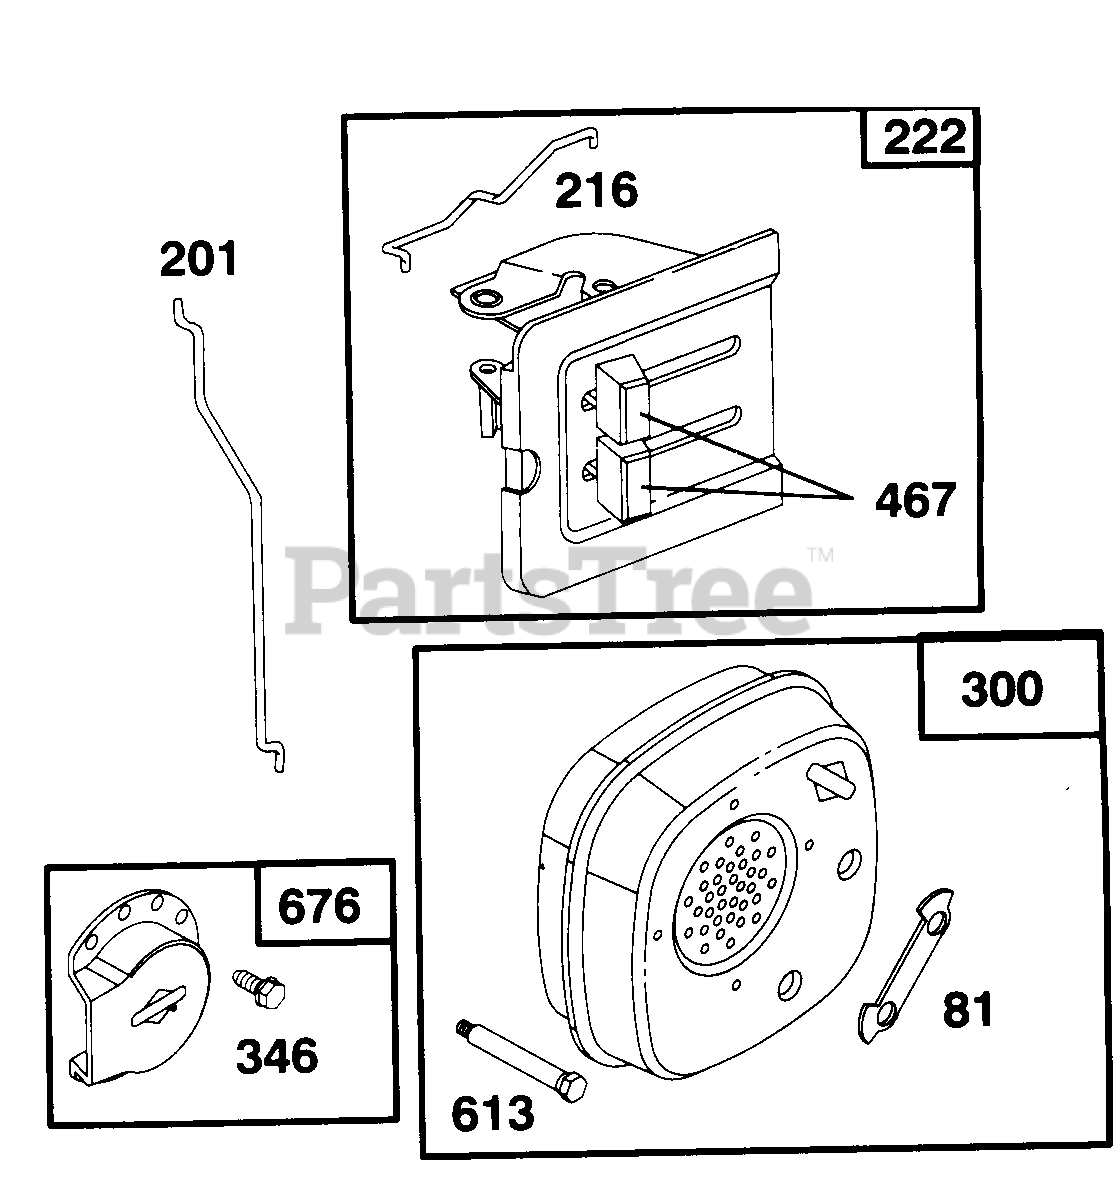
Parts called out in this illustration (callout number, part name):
81	Lock Screw
201	Link--Governor
216	Link--Choke
222	Panel--Control
300	Muffler--Exhaust
346	Screw Sem
467	Knob--Control
613	Screw Hex Head
676	Deflector Exhaust
